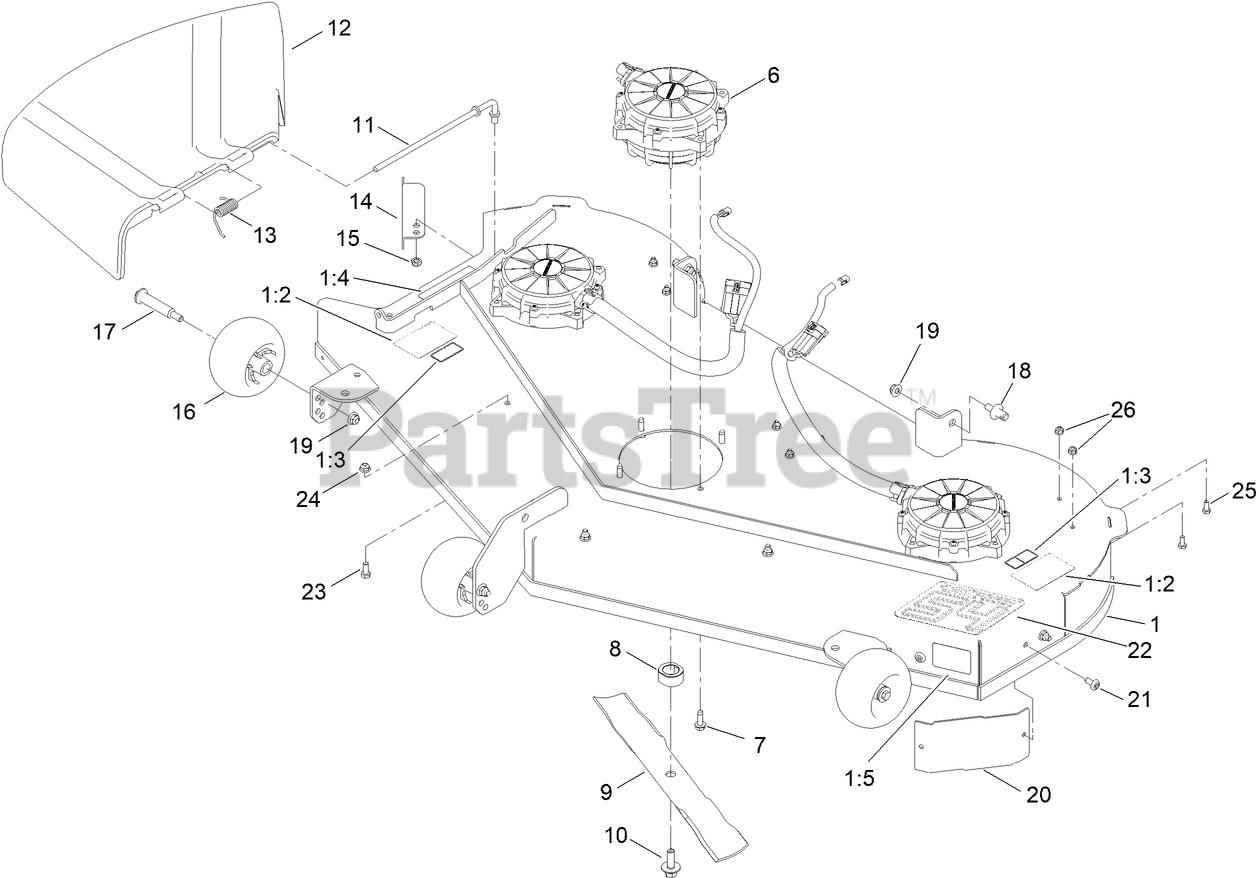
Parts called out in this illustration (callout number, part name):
1	54 IN DECK AND DECAL ASM
1:2	DECAL-DANGER, DECK
1:3	DECAL-NO SPRAY
1:4	DECAL-DANGER
1:5	DECAL-SCALP, ANTI
6	MOTOR-DECK
7	SCREW-THD ROLL, HWH
8	DRIVER-BLADE
9	BLADE-18.75 IN, COMBINATION
10	BOLT-BLADE, SEMS
11	ROD-PIVOT
12	DEFLECTOR-DISCHARGE
13	SPRING-TORSION
14	BAFFLE-CUTOFF
15	NUT-HEX
16	ROLLER-SCALP, ANTI
17	BOLT-SHOULDER
18	PIN-DECK
19	NUT-HF, NI
20	BAFFLE-CORNER
22	DECAL - DECK, 54
23	SCREW-HH
24	NUT-HF
25	SCREW-HH
26	NUT-FLANGE, NI
